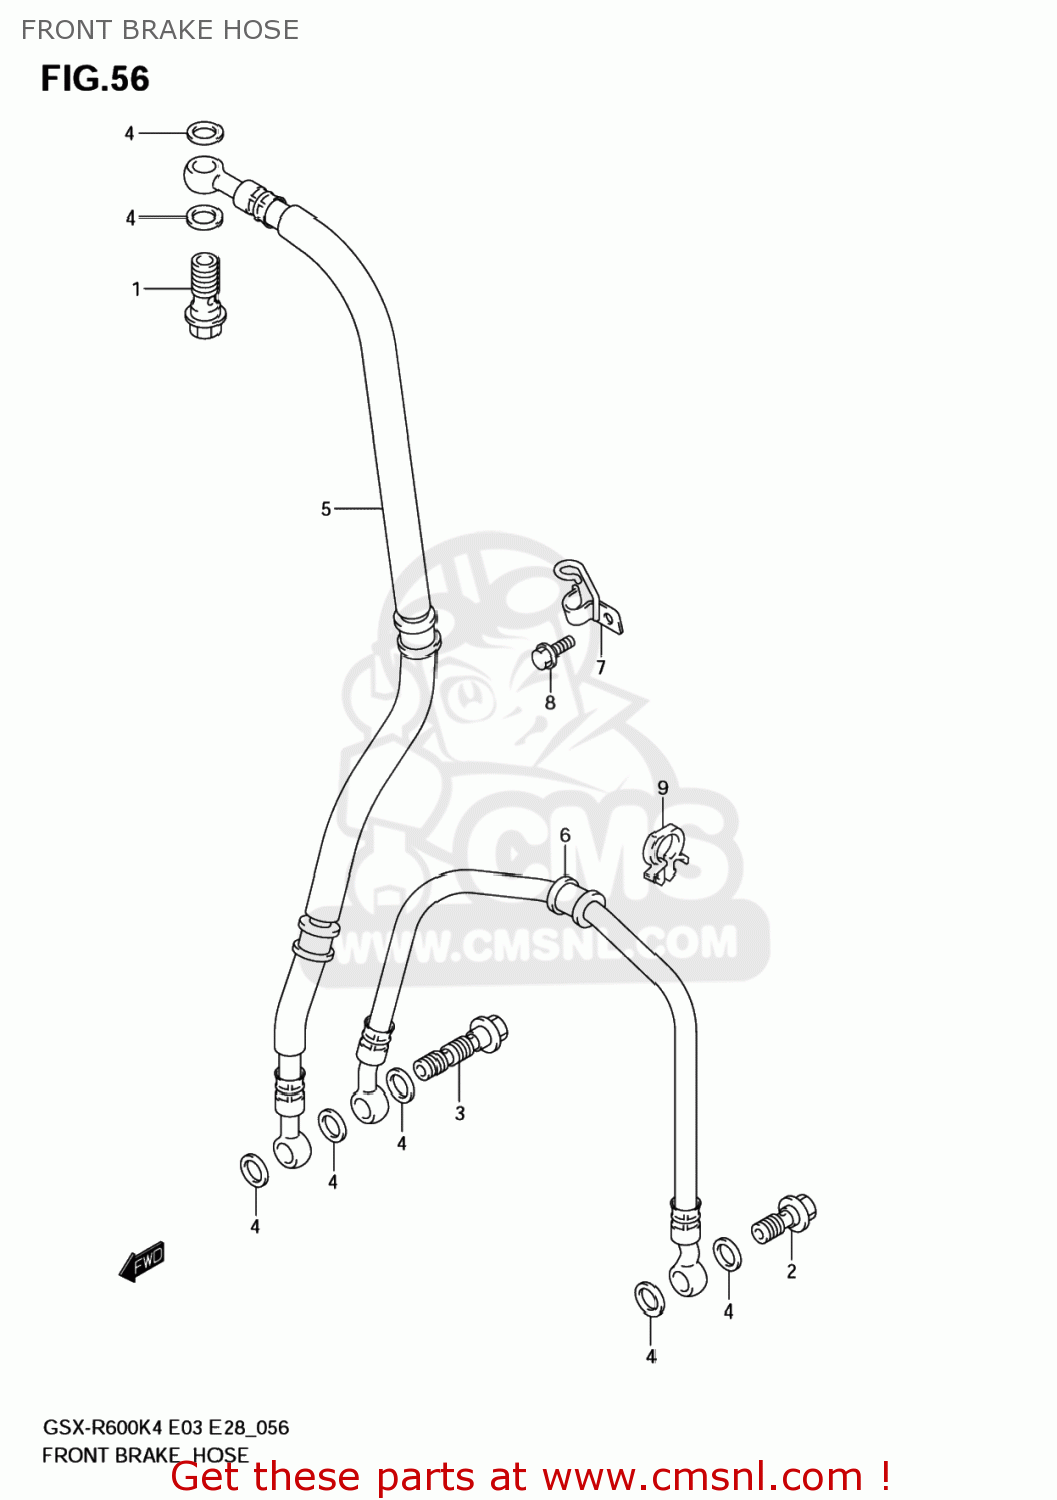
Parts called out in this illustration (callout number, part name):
1	BOLT UNION
2	BOLT UNION
3	BOLT UNION
4	WASHER(10X15X1.5)
5	HOSE COMP,FR B
6	HOSE COMP,FR B
7	CLAMP,FR BRAKE HOSE
8	BOLT
9	CLAMP
